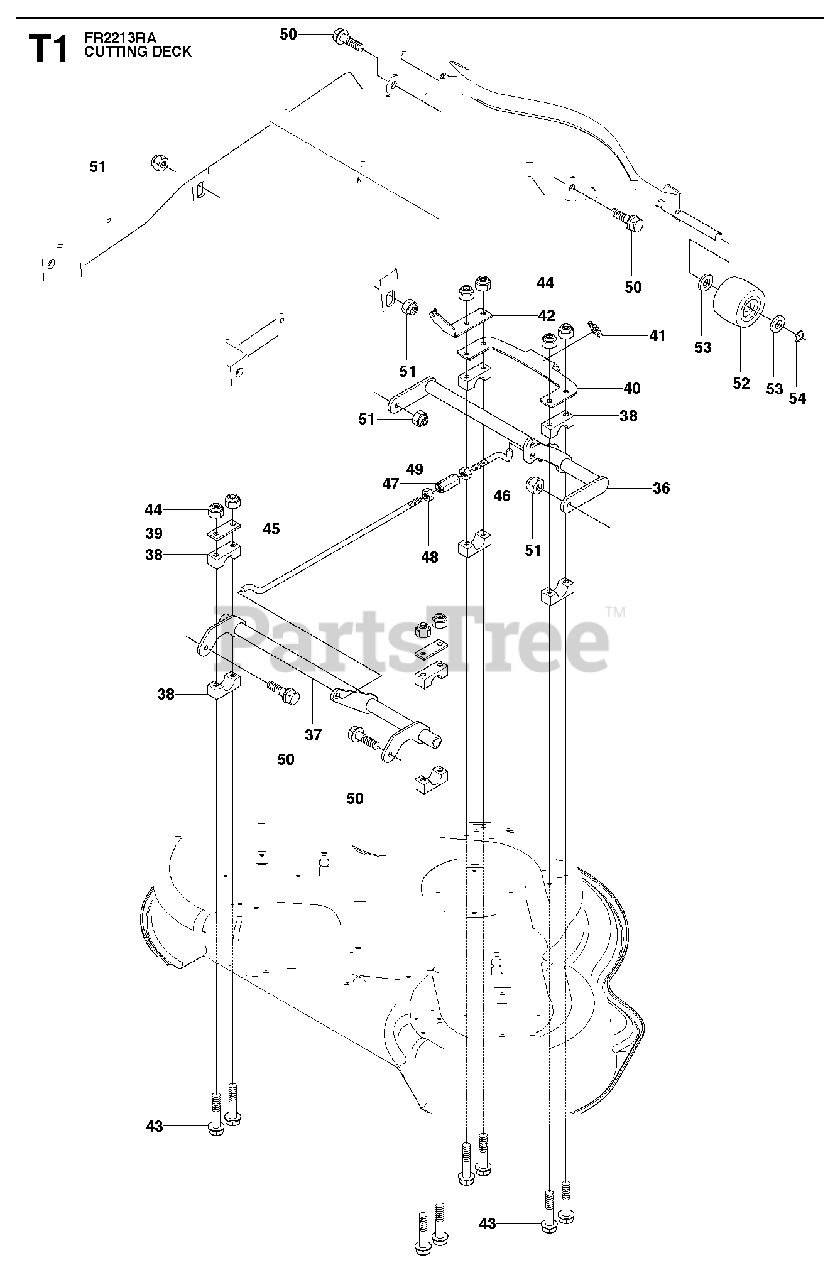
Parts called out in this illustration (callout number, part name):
44	LOCKNUT M8
51	LOCKNUT M8
52	DECK ROLLER, FRONT
54	RETAINING RING SGA 15
